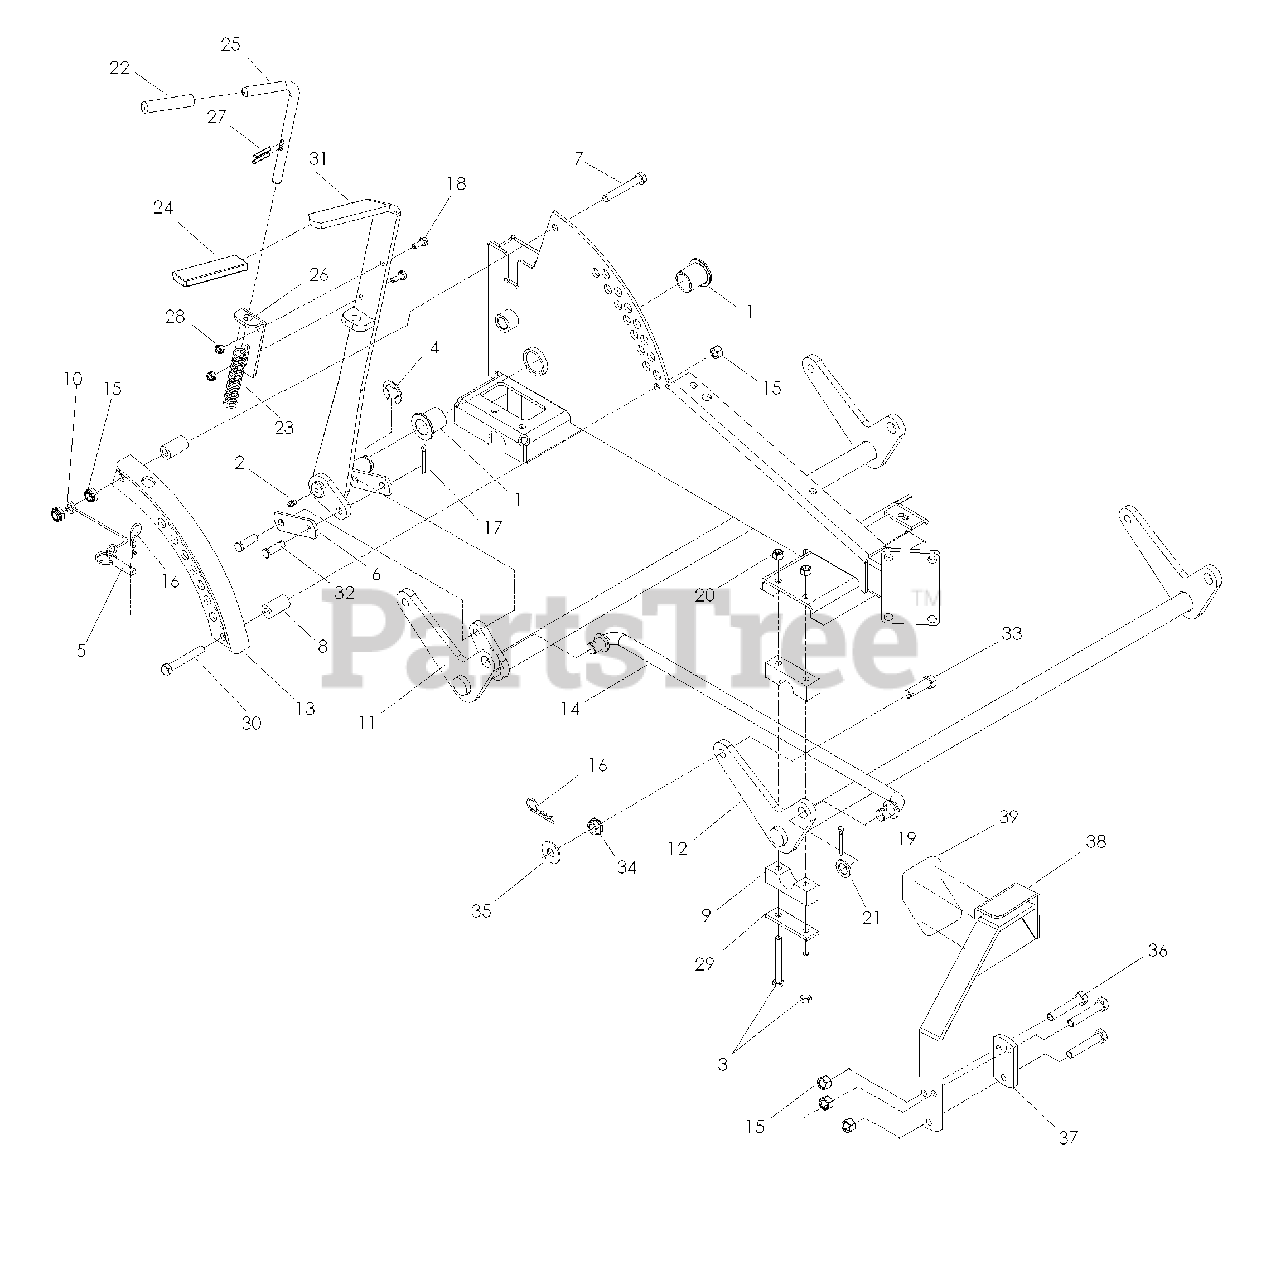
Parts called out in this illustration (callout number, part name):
3	HCS, 5/16 -18 x 2 3/4
4	RING-E, 7/8
5	PIN LIFT, 1/2 x 2, W/RINGS
7	HCS, 3/8 -16 x 2 3/4
9	BLOCK-PILLOW
11	REAR LIFT SHAFT
12	FRONT LIFT SHAFT
13	ADJUSTMENT PLATE
14	CROSS LINK
15	NUT 3/8-16 HEX NYLOC
16	PIN HAIR .120 x 2 1/2
17	PIN COTTER
18	HCS 1/4 -20 x 3/4
19	PIN COTTER 5/32 x 1 1/4
20	NUT 5/16-18 HEX NYLOC
22	GRIP, VINYL
23	SPRING, COMPRESSION
24	GRIP, LIFT LEVER
25	PIN 1/2 x 6.69 "L"
27	PIN GROOVED, 3/16 x 1 1/4
28	NUT 1/4 -20, CENTERLOCK
29	REINFORCED BAR
30	HCS 3/8 -16 x 2 1/2
31	LIFT LEVER
32	PIN CLEVIS, 3/8 x 1 1/8
33	HCS 7/16 -14 x 1 1/2
34	NUT 7/16 -14 WHZLCK
35	WASHER 7/16 FLAT
36	HCS 3/8 -16 x 1 1/2
37	PLATE, TIGHTENING
38	LIFT PEDAL
39	PAD, ANTI-SKID
